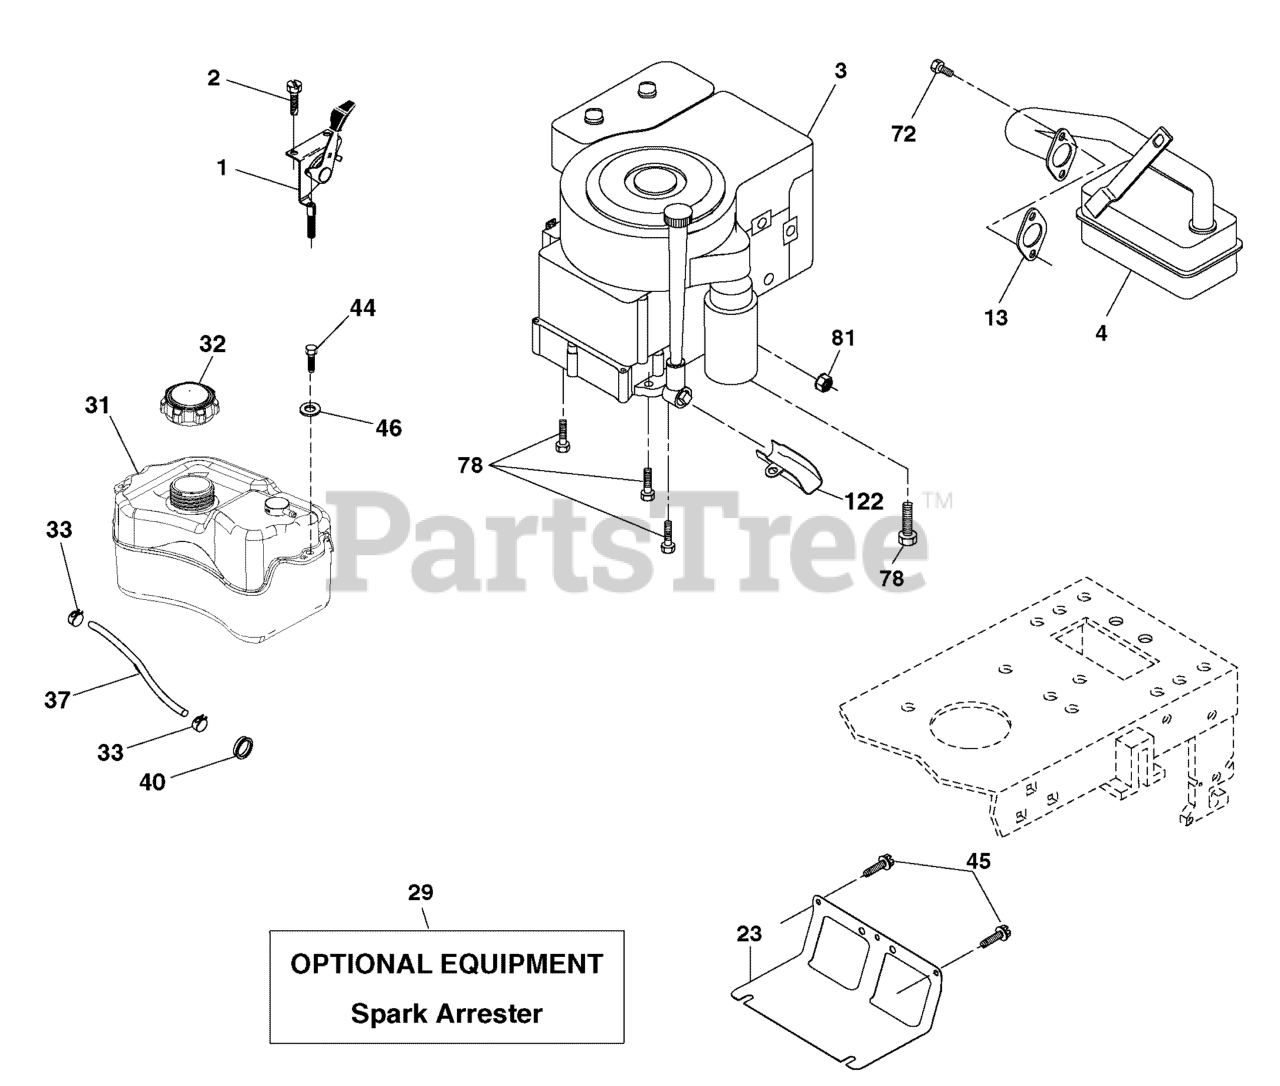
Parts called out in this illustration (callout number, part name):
1	CONTROL Th/Ch
2	SCREW, Hex Thd Cut 1/4-20 x 1/2
3	ENGINE, B&S 21B807-1453-B1
4	MUFFLER, Exhaust B&S
13	GASKET. Eng 1 313 Id Tin Plated
23	SHIELD, BRN/DBR Guard
29	KIT, Spark Arrestor (Flat Scrn)
31	TANK, Fuel Front
32	CAP, Fuel
33	CLAMP, Hose
37	FUEL LINE, 20"
40	BUSHING, Snap Nyl Blk Fuel Line
44	SCREW, Thdrol 1/4-20 x 3/4
45	SCREW, Hex Wsh Thdrol 3/8-16
46	WASHER, 9/32 x 7/8 x 16 Ga.
72	SCREW, Socket Hd 5/16-18 x .75
78	SCREW, 3/8-16 x 1-1/4
81	NUT, Keps Hex 1/4-20 unc
122	EXTENSION, Drain Oil
